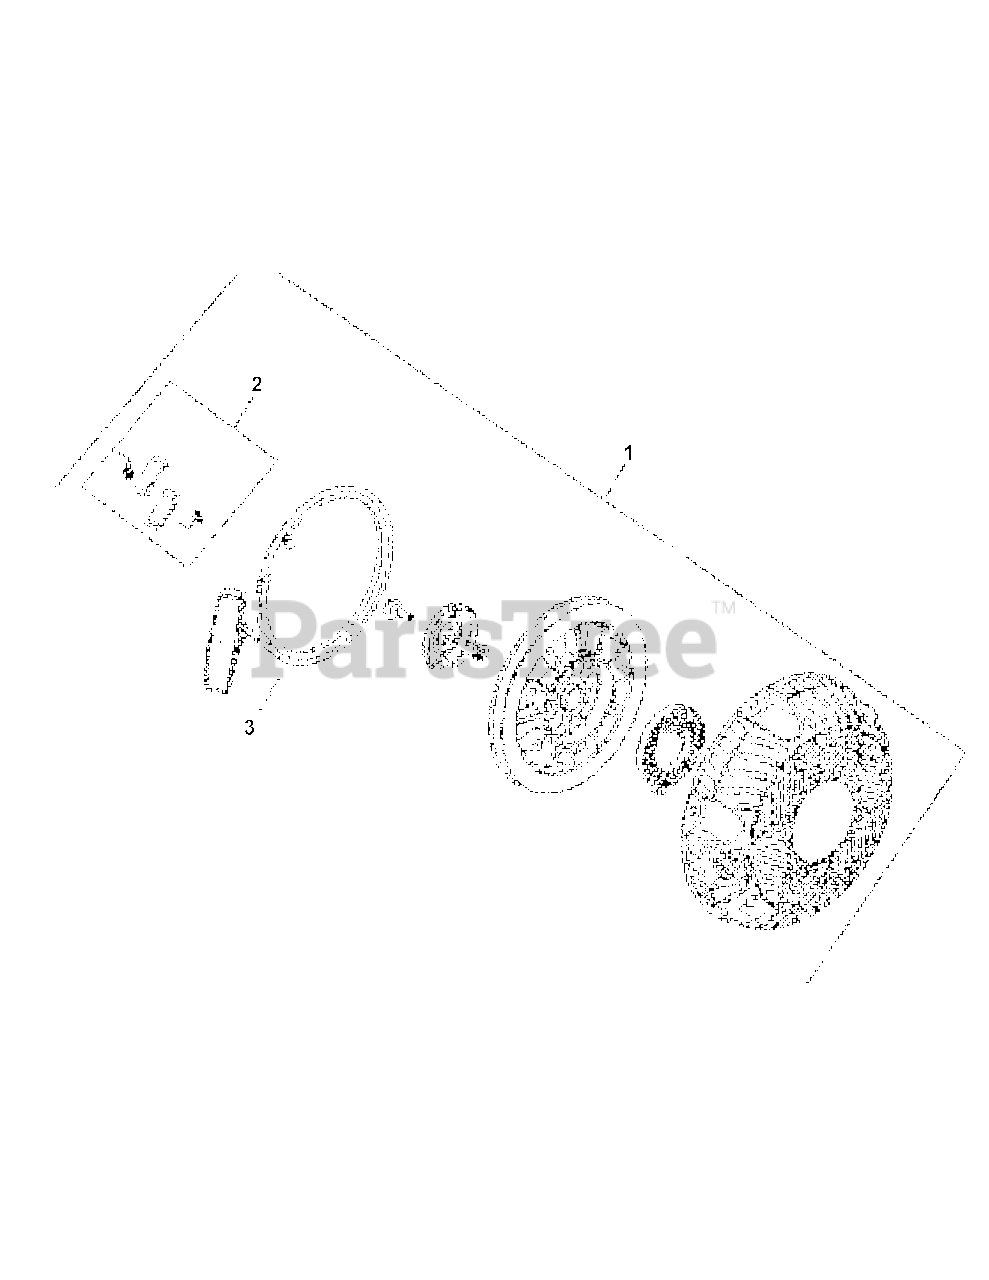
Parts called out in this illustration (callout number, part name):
1	Retractable Starter Assembly
2	Pawl Repair Kit
3	Starter Rope W/Handle Kit
